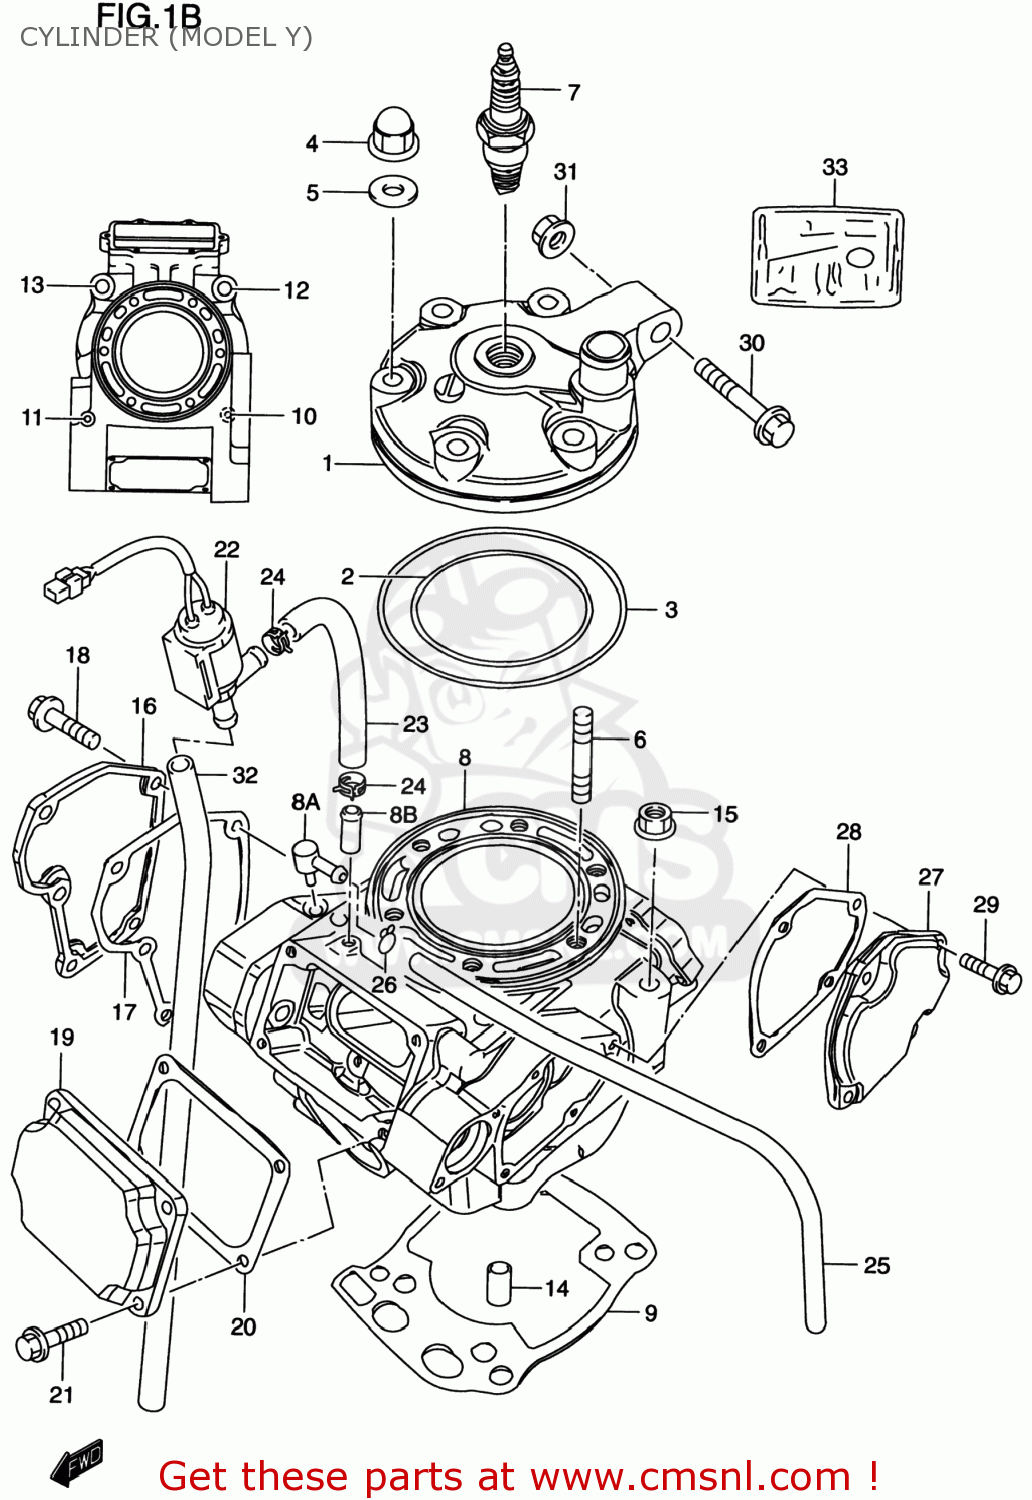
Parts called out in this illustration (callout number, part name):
1	HEAD,CYLINDER
2	O RING,CYLINDER HEAD NO.1
3	O RING,CYLINDER HEAD NO.2
4	NUT
5	GASKET(8.5X17X2.3) (NAS)
6	BOLT,STUD
7	PLUG,SPARK(R6918B-7)
8	CYLINDER SET
8A	UNION,BREATHER HOSE
8B	UNION
9	GASKET,CYLINDER (NAS)
10	STUD 10X30
11	STUD BOLT (L:40)
12	STUD BOLT (L:70)
13	STUD BOLT
14	PIN(13X10.4X20)
15	NUT
16	COVER,CYLINDER NO.1
17	GASKET,CYLINDER COVER NO.1 (NAS)
18	BOLT
19	COVER,CYLINDER NO.2
20	GASKET,CYLINDER COVER NO.2
22	SOLENOID VALVE ASSEMBLY
23	HOSE(6X10X600)
24	CLIP
25	HOSE(5X8.2X600)
26	CLIP
27	COVER,CYLINDER NO.3
28	GASKET,CYLINDER COVER (NAS)
29	BOLT
30	BOLT(10X48)
31	NUT
32	HOSE(6X10X600)
33	GASKET SET (NAS)
